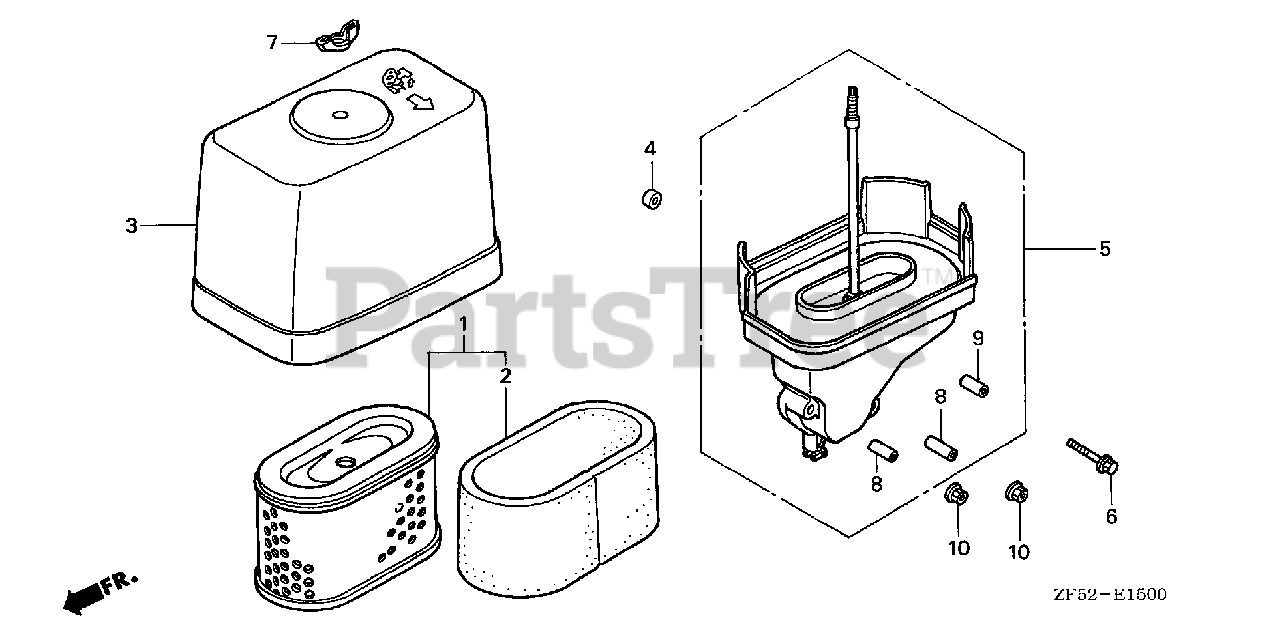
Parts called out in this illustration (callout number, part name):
1	ELEMENT, AIR CLEANER (PLASTIC BASE)
2	FILTER (OUTER)
3	COVER, AIR CLEANER
5	ELBOW, AIR CLEANER
6	BOLT, FLANGE (6X35) (CT200)
7	NUT, TOOL BOX SETTING
8	COLLAR, AIR CLEANER
9	COLLAR, AIR CLEANER
10	NUT, FLANGE (6MM)
